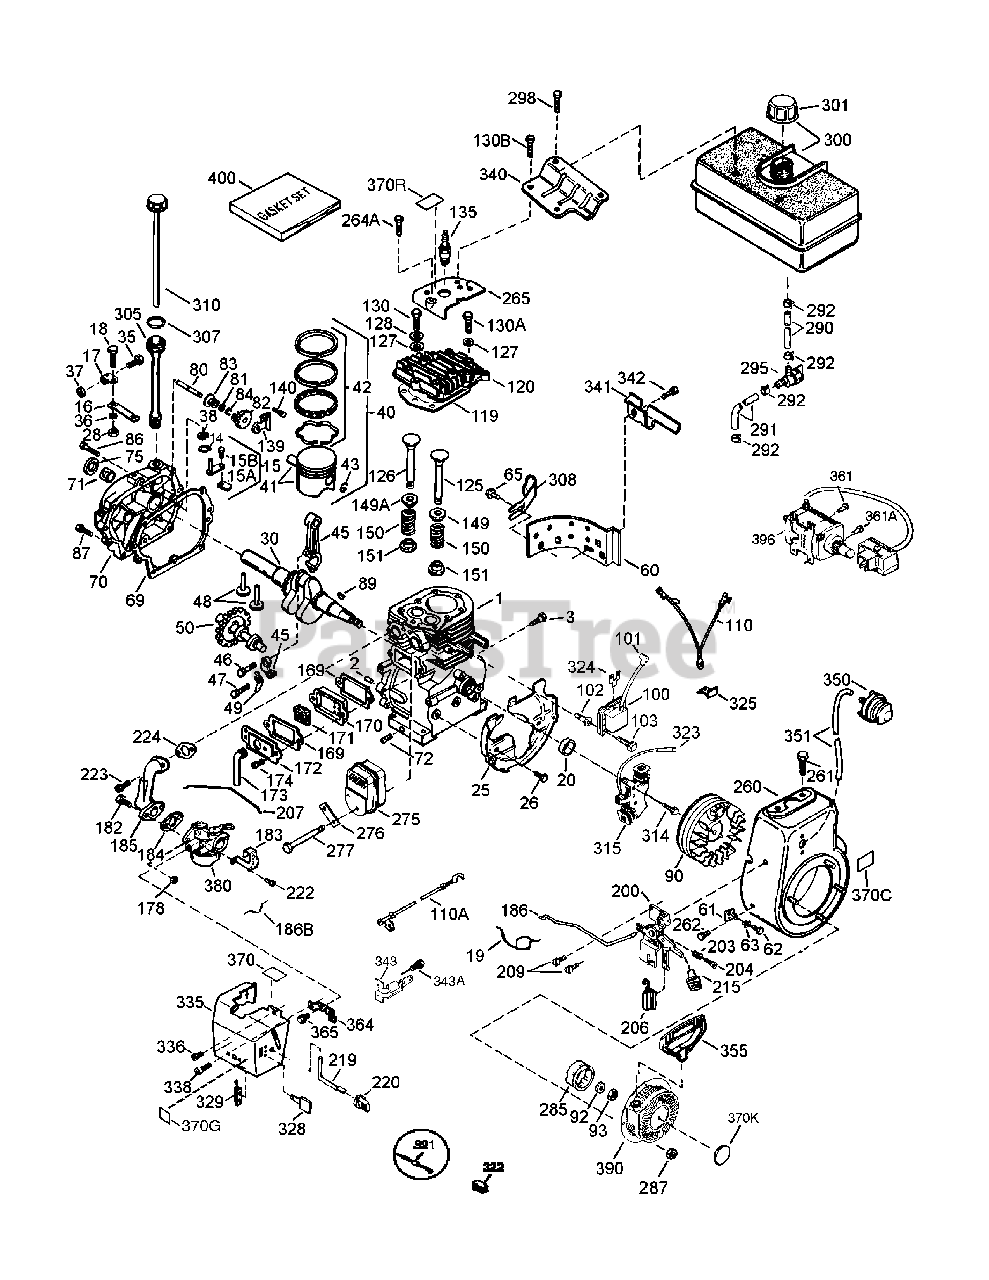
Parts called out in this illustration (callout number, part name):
2	Dowel Pin
3	Screw (1/4-20x1/2")
4	PURCHASE LOCALLY
5	Extension Cap
15	Governor Rod
15A	Governor Yoke
15B	Screw (6-40x5/16")
16	Governor Lever
17	Governor Lever Clamp
18	Screw (T-15)
19	Speed Control Spring
25	Blower Housing Baffle
26	Screw (1/4-20x19/32")
28	Lock Nut (8-32)
30	Crankshaft
35	Screw (10-32x3/4")
36	Lock Washer
37	Lock Nut (10-32)
38	Retaining Ring
40	Piston, Pin & Ring Set (Std.)
40	Piston, Pin & Ring Set (.010)
40	Piston, Pin & Ring Set (.020)
41	Piston & Pin Assy. (Std.)
41	Piston & Pin Assy. (.010)
41	Piston & Pin Assy. (.020)
42	Ring Set (Std.)
42	Ring Set (.010)
42	Ring Set (.020)
43	Piston Pin Retaing Ring
45	Connecting Rod Assy.
47	Connecting Rod Bolt
48	Valve Lifter
49	Oil Dipper
60	Blower Housing Extension
65	Screw (10-24x1/2")
69	Cylinder Cover Gasket
70	Cylinder Cover
71	Bearing Cover
80	Governor Shaft
82	Governor Gear Assy.
83	Governor Spool
84	Retaining Ring
86	Screw (1/4-20x1-3/16")
87	Screw (1/4-20x1-11/16")
89	Flywheel Key
92	Belleville Washer
93	Flywheel Nut
100	Solid State Ignition
101	Spark Plug Cover
102	Mounting Stud
103	Screw (T-15)
110	Wire Assy.
110A	Ground Wire
119	Cylinder Head Gasket
120	Cylinder Head
125	Exhaust Valve (Std.)
125	Exhaust Valve (1/32" OS)
126	Intake Valve
128	Belleville Washer
130	Screw (5/16-18x1-1/2")
130A	Screw (5/16-18x1-25/32")
135	Spark Plug
139	Governor Gear bracket
140	Screw (10-24x1/2")
149	Valve Spring Cap
149A	Valve Spring Cap
150	Valve Spring
151	Valve Spring Keeper
169	Valve Cover Gasket
170	Breather Body
171	Breather Element
172	Valve Cover
173	Breather Tube
174	Screw (10-24x1/2")
178	Nut & Lock Washer (1/4-28)
182	Screw (1/4-20x1")
183	Choke Bracket
184	Carb Intake Pipe Gasket
185	Intake Pipe
186	Governor Link
186B	Choke Spring
200	Control Bracket
203	Compression Spring
204	Screw (T-10)
207	Throttle Link
209	Screw (10-32x1/2")
215	Control Knob
219	Choke Rod
220	Choke Knob
222	Screw (10-32x1/2")
223	Screw (T-30)
224	Intake Pipe Gasket
260	Blower Housing
261	Screw (5/16-18x3/4")
262	Screw (5/16-18x9/16")
264A	Screw (1/4-20x5/8"
265	Cylinder Head Cover
276	Locking Plate
277	Screw (5/16-18x4-3/16")
285	Starter Cup
287	Nut & Lock Washer (1/4-28)
291	Fuel Line
292	Fuel Line Clamp
298	Screw (1/4-15x3/4")
305	Oil Fill Tube
308	Fill Tube Clip
314	Screw (1/4-20x3/4")
315	Alternator Coil
322	Connector Body
325	Wire Clip
328	Ignition Keys
335	Carburetor Cover
336	Screw (10-32x1/2")
338	Screw (10-32x3/8")
340	Fuel Tank Bracket
341	Fuel Tank Bracket
342	Screw (1/4-20x19/32")
343	Key Switch Bracket
343A	Screw (10-32x23/64")
350	Primer Assy.
351	Primer Line
355	Starter Handle
361	Screw (T-30)
364	Carburetor Cover Bracket
365	Screw (8-32x27/64")
370B	Instruction Decal
370C	Primer Decal
370D	Warning Decal
370K	Starter Decal
370R	Warning Decal
380	Carburetor
390	Recoil Starter Assy.
396	Electric Starter Motor
400	Gasket Set
